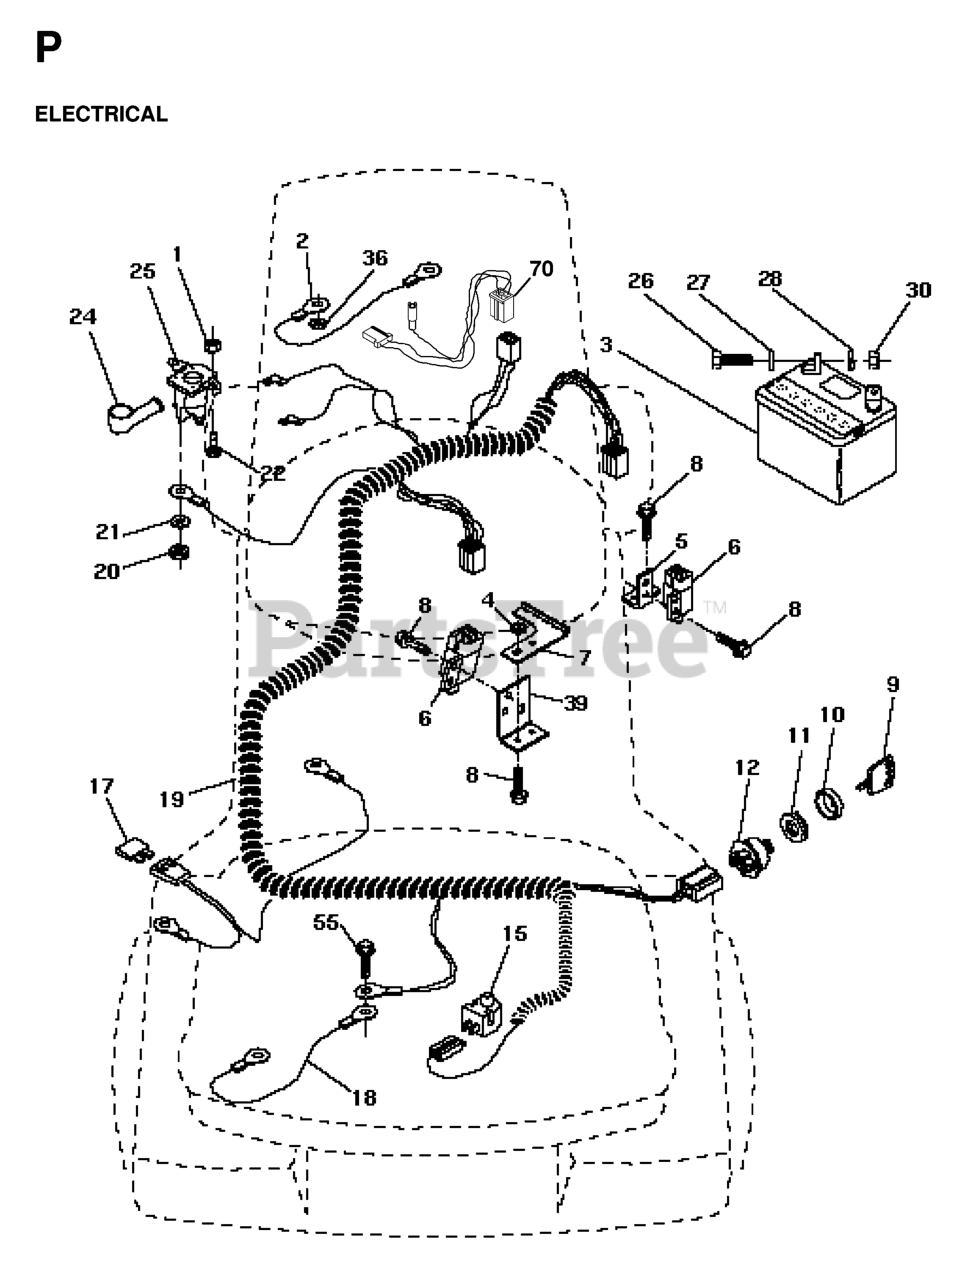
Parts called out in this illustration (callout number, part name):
1	Nut, Keps Blk Hex 1/4-20 UNC
2	CABLE.BATTERY.6GA.16"RED
3	REPL BY 532 12 38-99
5	BRACKET LT
6	SWITCH INTERLOCKT
7	KEEPER, ACTUAT. L.R.
9	KEY MLD GEN DELTA
10	COVER SWITCH KEY
11	NUT, IGNITION
12	IGNITION SWITCH
15	RP.SWITCH.PLUNGER.NC.GRAY
18	CABLE ASSY
19	HARNESS, IGN FEND
20	NUT
21	LOCKWASHER
22	BOLT
24	TERMINAL COVER
25	SOLINOID
26	BOLT.HEX.1/4.X.3/4.DICHROMATE
28	LOCKWASHER
30	NUT
36	Washer, Lock, Internal Tooth 1/4
55	Screw 5/16-18 x 1/2 Hex, Self Tapping 5/16-18 x 1/2
70	HARNESS, ENGINE
